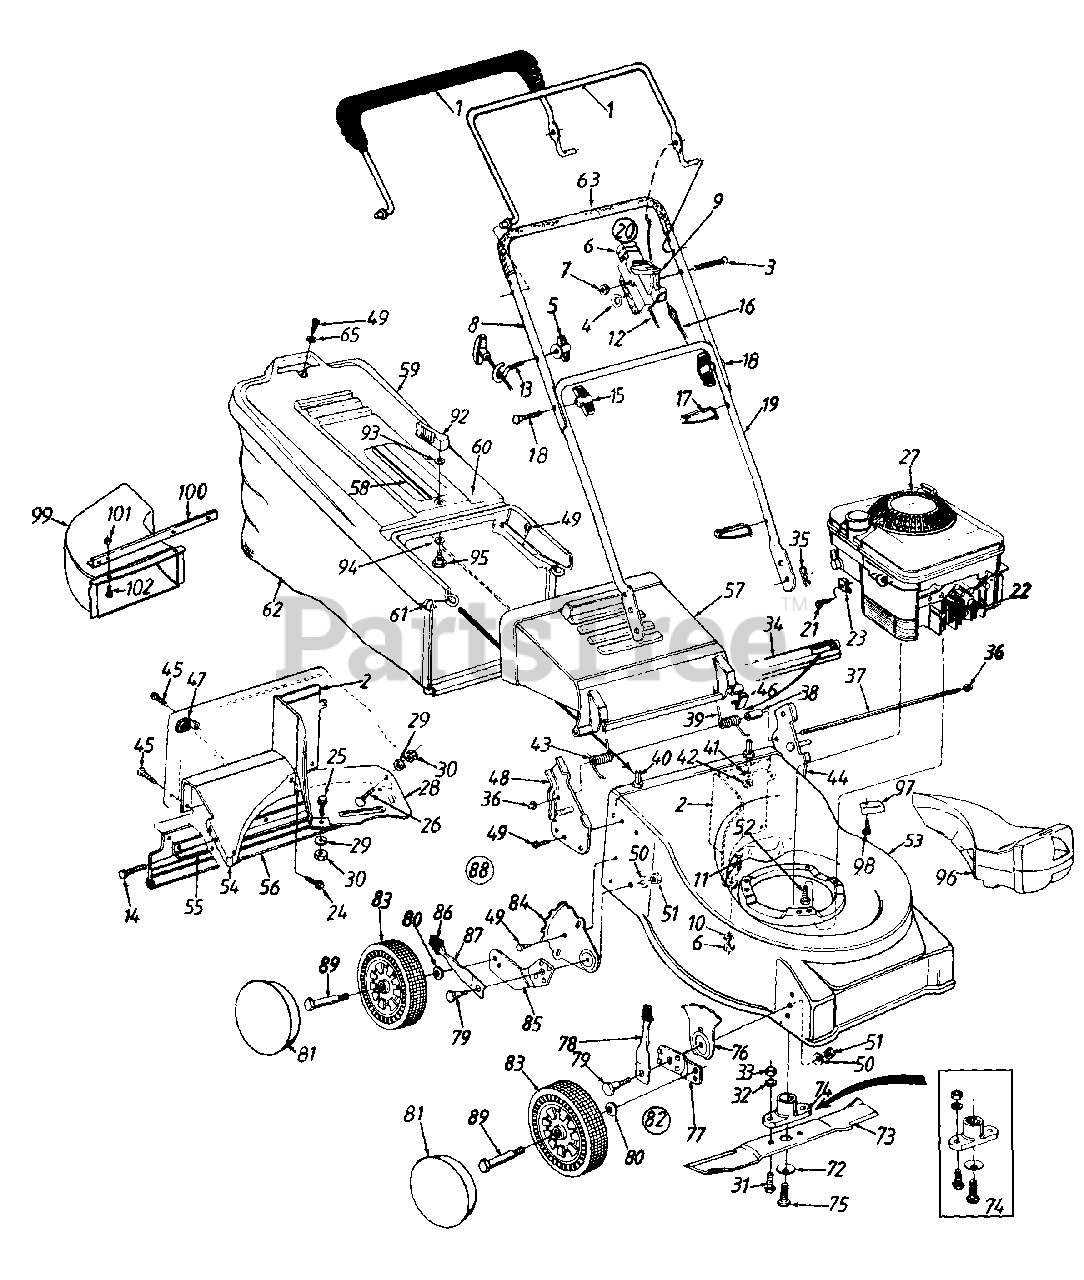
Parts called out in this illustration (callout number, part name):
4	Spr. Wash..66" I.D.
5	Handle Knob 1/4-20 Thd.
6	Throttle Body
7	Hex L-Nut 1/4-20 Thd.
10	Bell-Wash. 1/4" I.D.
11	Hex Bolt 1/4-20 x .85"
12	Throttle Control Wire - 55"
13	Rope Guide
14	Hex B-Tap Scr. 1/4 x .38" Lg.
15	Hand Knob
16	Control Cable - 40.5"
17	Cable Tie
18	Curved Hd. Bolt 5/16-18 x 2" Lg.
20	Throttle Box Comp.
21	Hex Self-Tap Scr. #10-32 x .62" Lg.
22	Spark Plug Boot
23	Cable Clamp
24	Hex B-Tap Scr. 1/4 x .38" Lg.
25	Hex Bolt 1/4-20 x .85" Lg.
26	Carriage Bolt 1/4-20 x .62" Lg.
27	Engine
30	Hex Nut 1/4-20 Thd.
31	Hex Bolt 3/8-24 x 1" Lg.
32	L-Wash. 3/8" I.D.
33	Mex Nut 3/8-24 Thd.
34	Seal - Extrusion
35	Int. Cotter Pin 5/16" Dia.
36	Cap Speed Nut
37	Hinge Pin 17.75" Lg.
38	Spacer .255" I.D.
39	Torsion Spring - L.H.
40	Shld. Pin 3/8-24 x 1.43" Lg.
41	L-Wash. 3/8" I.D.
42	Hex Jam Nut 3/8-24 Thd.
43	Torsion Spring - R.H.
46	Deflector Plug
47	Corner Plug
50	Bell-Wash .39" I.D.
51	Hex Nut 3/8-16 Thd.
52	Hex L-Wash. Hd. Scr. 3/8-16 x 1" Lg.
57	Rear Chute Deflector
58	Hardtop Handle
59	Hardtop Bag Cover
60	Rear Catcher Frame
62	Grass Bag
63	Foam Grip
65	Fl-Wash. .281" I.D.
72	Bell-Wash. .39" I.D.
73	21" Blade
74	Blade Adapter Kit
75	Hex Bolt 3/8-24 x 1.5" Lg.
76	Height Adj.. Plate
78	Spring Lever Ass'y. w/Knob
79	Shld. Bolt .50" Dia. x .357"
80	Bell-Wash..38" I.D. x .88" O.D.
81	Hub Cap (5-1/2" Dia.)
82	Height Adj. Ass'y. Comp.- R H.
83	Wheel Ass'y. Comp.
84	Index Plate
85	Pivot Bar - R.H.
86	Spring Lever Knob
87	Spring Lever
88	Rear Height Adj. Ass'y. Comp.- R.H
89	Axle Bolt
92	Grass Catcher Locking Knob
93	Internal L - Wash. 1/4" I.D.
94	Wave Washer 3/8" I.D.
95	Shld. Bolt .342" Dia. x .268"
96	Mulching Plug
97	Stop Bracket
98	Hex Tap Scr. 3/8-16 x .75" Lg.
99	Chute Deflector
101	Hex L-Nut 1/4-20 Thd.
102	Mach. Scr 1/4-20 x .5" Lg.
